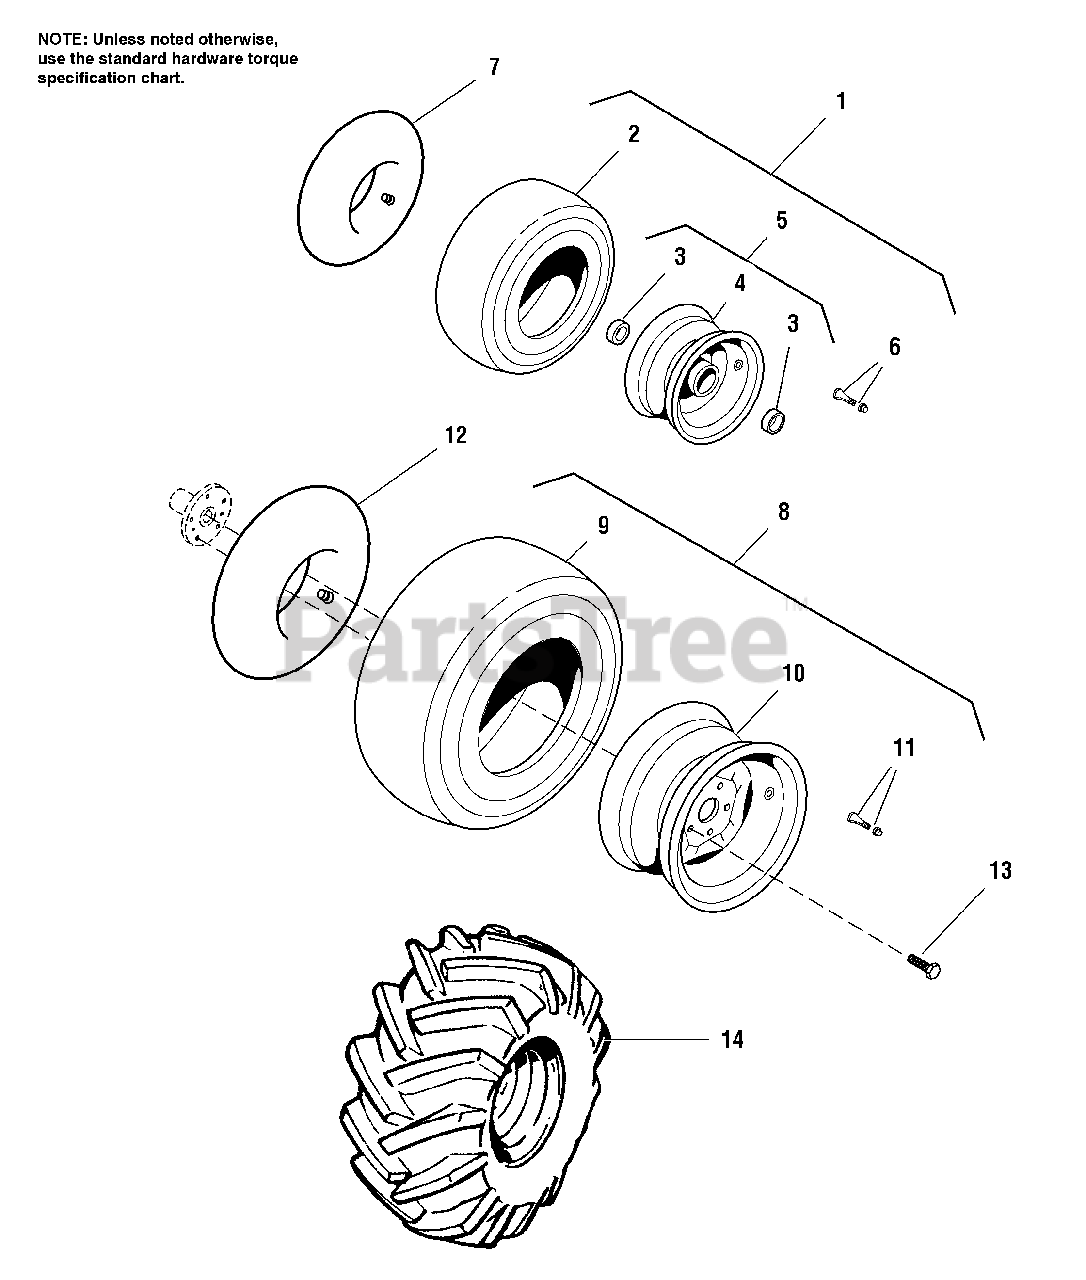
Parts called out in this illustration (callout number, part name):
1	WHEEL & TIRE ASSEMBLY, 16x6.50-8, Turf Tread
2	TIRE, Turf Tread, 16x6.50-8
3	CUP, Bearing
4	WHEEL, Metallic Gray
5	WHEEL & BEARING CUP ASSEMBLY, Front, Metallic Gray
6	VALVE STEM & CAP ASSEMBLY, Front Wheel
7	INNER TUBE, 16x6.50-8
8	WHEEL & TIRE ASSEMBLY, 23x10.50-12, Turf Tread
9	TIRE, Turf Tread, 23x10.50-12
10	WHEEL ASSEMBLY, Rear, Metallic Gray
11	VALVE STEM & CAP ASSEMBLY, Rear Wheel
12	INNER TUBE, 23x10.50-12
14	TIRE, Ag-Tread, 23x10.50-12
